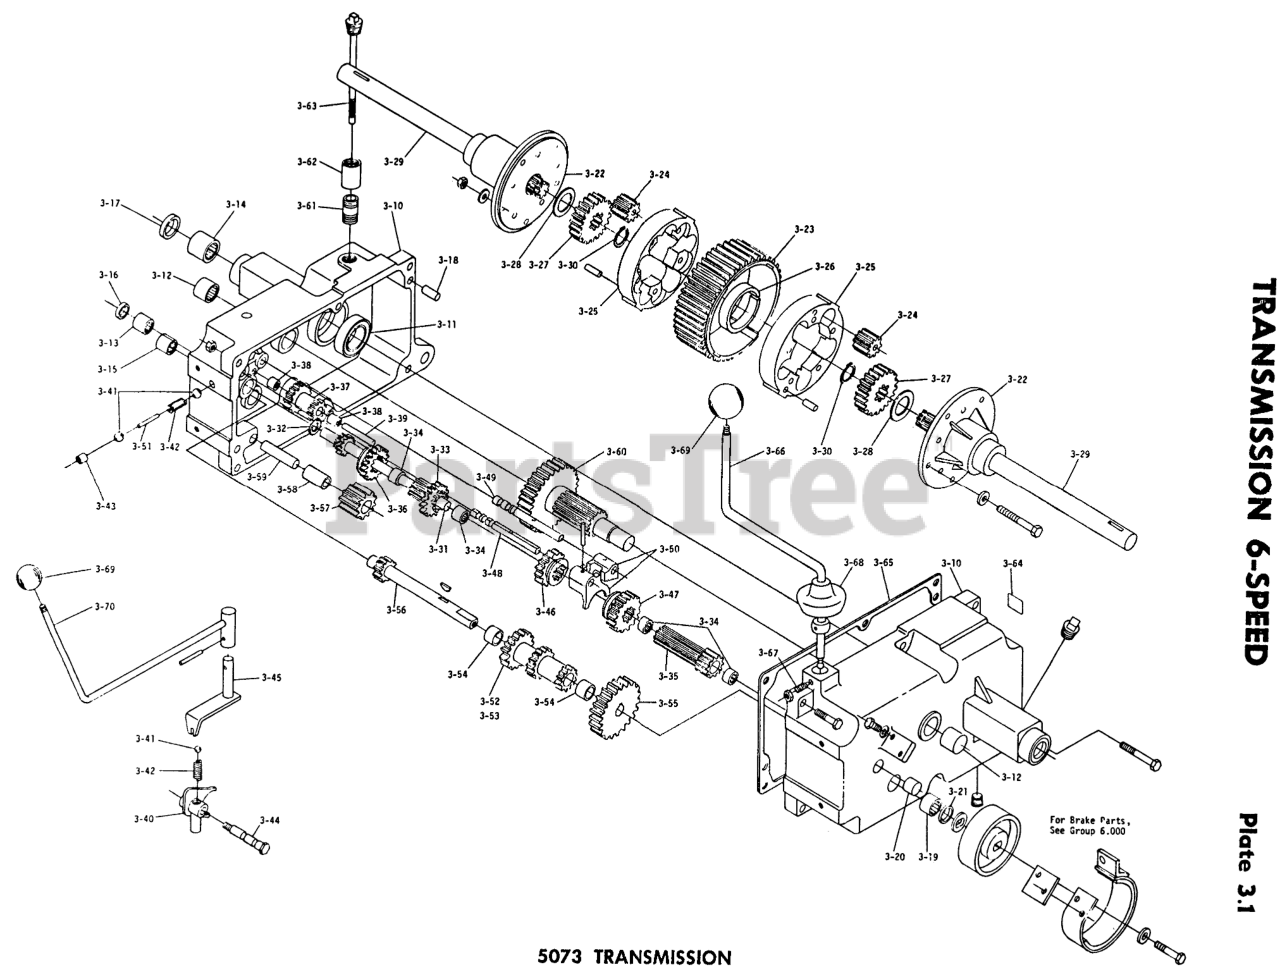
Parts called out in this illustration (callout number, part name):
3-10	Bolt Hex 3/8-16 x 1
3-10	Bolt, 3/8 16 x 2
3-12	BEARING-NEEDLE
3-13	BEARING-NEEDLE
3-15	BEARING-NEEDLE
3-16	SEAL-OIL
3-17	SEAL-OIL
3-18	PIN-DOWEL
3-19	BEARING-NEEDLE
3-21	SEAL-OIL
3-22	Bolt Hex 3 1/4
3-22	3/8-16 E.S.
3-22	Washer
3-25	BULLT 252
3-27	SIDE GEAR
3-31	SHAFT-INPUT
3-32	WASHER-THRUST
3-33	GEAR
3-34	BEARING-NEEDLE
3-35	GEAR
3-36	GEAR-SLIDING
3-38	BEARING-NEEDLE
3-39	GEAR-SHAFT REDUCTION
3-41	BALL-DETENT
3-43	CUP-PLUG
3-44	BOLT-DETENT
3-45	SHIFT ASM
3-46	GEAR-HI AND 2ND
3-47	GEAR-LOW AND REVERSE
3-48	RAIL-SHIFT
3-49	RAIL-REAR SHIFT
3-50	FORK-SHIFT
3-50	PIN-ROLL
3-51	PIN-SHIFT
3-52	GEAR-CLUSTER
3-54	BUSHING-BRONZE
3-55	GEAR-CLUSTER SHAFT
3-56	Key
3-57	GEAR/BUSHING ASM-REVERSE IDLER
3-58	BUSHING
3-59	PIN-DIFFERENTIAL
3-61	Nipple Close 1/2 Pipe
3-62	Coupling 1/2 Pipe
3-64	Decal
3-65	GASKET-TRANSMISSION
3-67	SETSCREW
3-67	Nut 1/4-20
3-68	COVER-DUST
3-70	PIN-SPIROL
